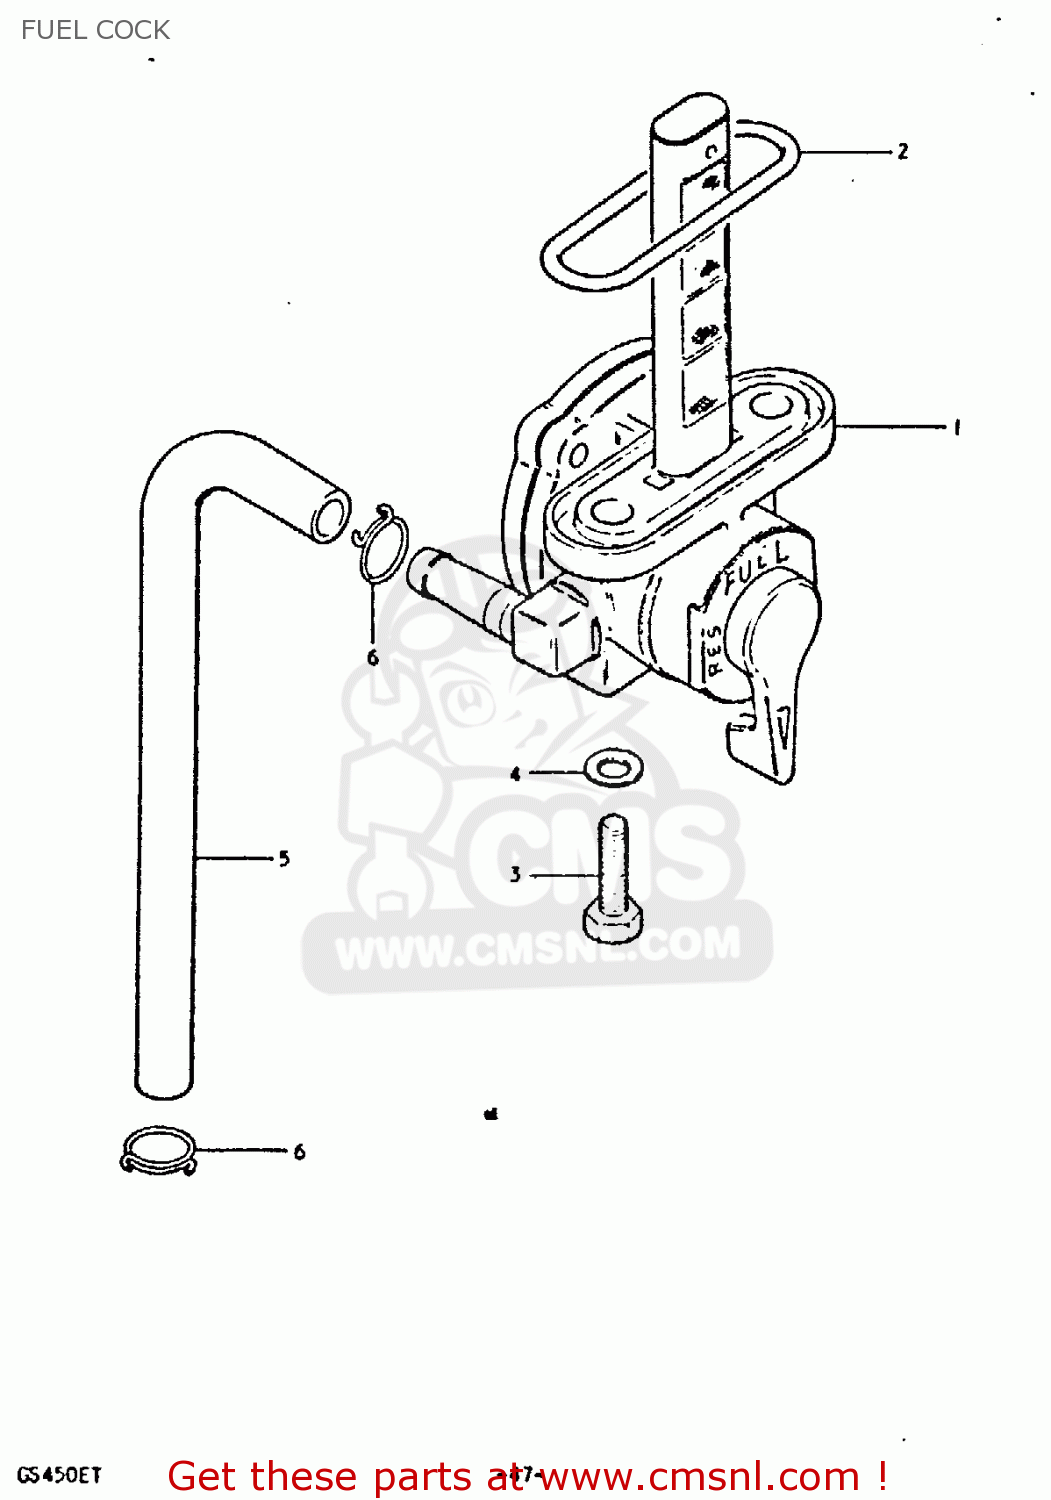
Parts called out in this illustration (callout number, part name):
1	COCK ASSEMBLY,FUEL
2	O RING
3	BOLT(6X20)
4	GASKET
5	HOSE
6	CLIP
